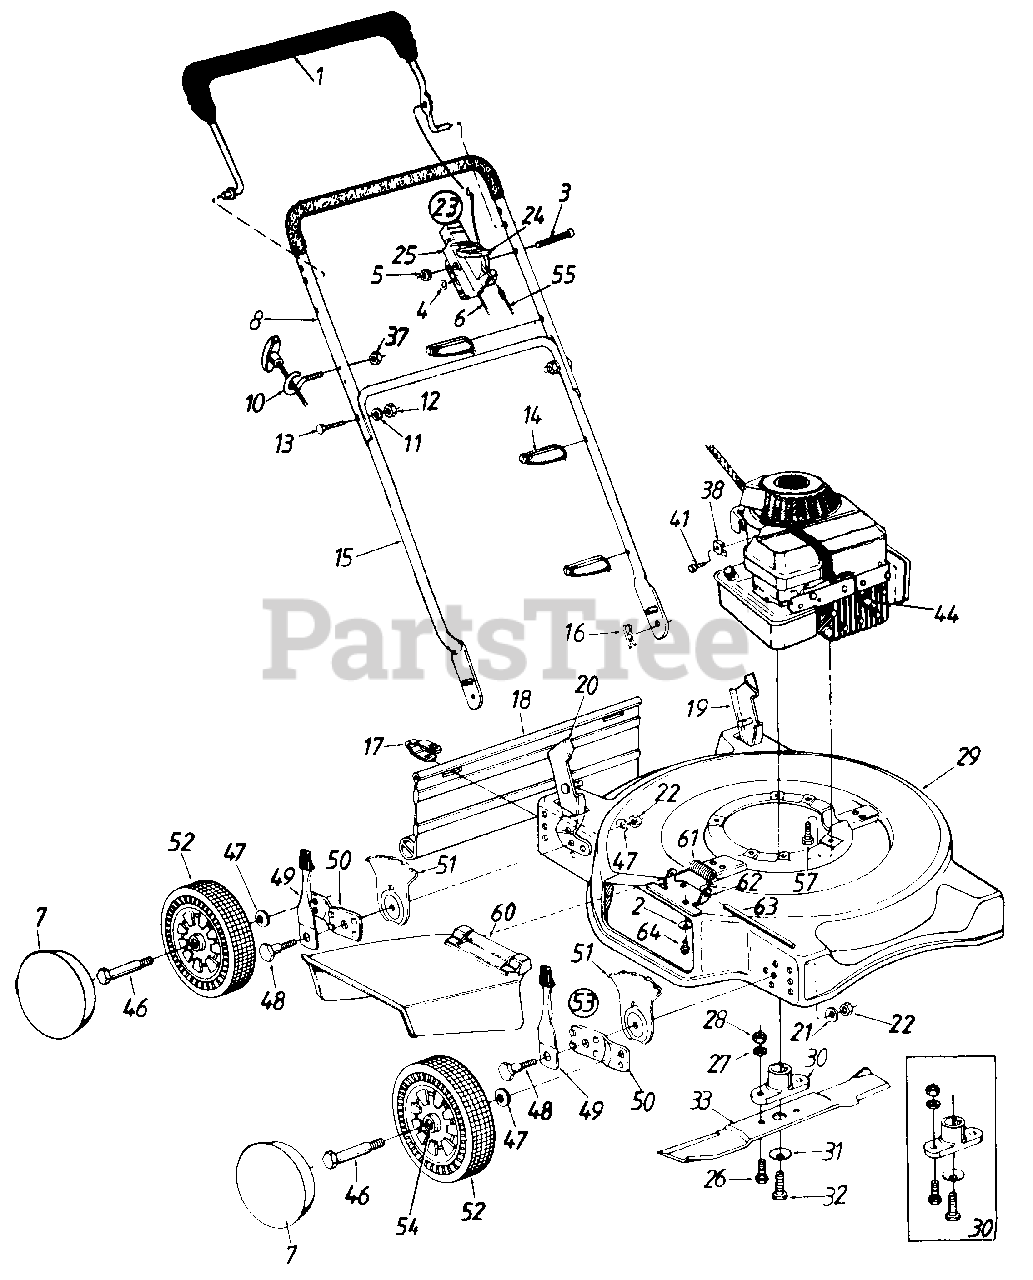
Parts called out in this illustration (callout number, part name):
1	Control Handle Ass'y.
2	Bell-Wash. 1/4" I.D.
3	Oval C-Sunk Scr.
4	Spr. Wash. .66" I.D.
5	Hex L-Nut 1/4-20 Thd.
6	Throttle Cable--51"
7	Hub Cap
11	L-Wash. 5/16" I.D.
12	Hex Nut 5/16-18 Thd.
13	Curved Carriage Bolt 5/16-18 x 1.38" Lg.
14	Cable Tie
15	Lower Handle
16	Hairpin Cotter
17	Hinge Clip
18	Rear Flap
19	Handle Bracket Ass'y.--L.H.
20	Handle Bracket Ass'y.--R.H.
21	Bell-Wash. .39" I.D. x 1.38"
22	Hex Nut 3/8-16 Thd.
23	Throttle Box Comp.
24	Throttle Lever
25	Throttle Body
26	Hex Bolt 3/8-24 x 1" Lg.
27	L-Wash. 3/8" I.D.
28	Hex Nut 3/8-24 Thd.
31	Bell-Wash. .39" I.D.
32	Hex Bolt 3/8-24 x 1.5" Lg.
33	20" Blade
37	Hex L-Nut 1/4-20 Thd.
38	Cable Clamp
41	Hex Self-Tap Scr. #10-32 x .62"
44	Spark Plug Boot
46	Axle Bolt
47	Bell-Wash. .400" I.D. x .88"
48	Shld. Bolt .50" Dia. x .357"
49	Spring Lever Ass'y. w/Knob
51	Height Adj. Plate
52	Wheel Ass'y. Comp.
53	Height Adj. Ass'y. Comp.--R.F. & L.R.
54	Wheel Bearing
55	Control Cable--39"
57	Hex L-Wash. Hd. Scr. 3/8-16 x 1.0" Lg.
60	Chute Deflector Ass'y.
61	Torsion Spring
62	Adapter Plate
63	Hinge Pin
64	Hex Self-Tap Scr. 1/4-20 x .5" Lg.
17036-0483	DECK ASSEMBLY-20INCHARCOAL - CHARCOAL GRAY (0483)
17036-0498	DECK ASSEMBLY-20IN(CUB YELLOW) - OLD CUB YELLOW (0498)
17036-0629	DECK ASSEMBLY-20INSILVER FLAK - SILVER FLAKE (0629)
17036-0638	DECK ASSEMBLY-20IN - MTD/TROY-BILT RED (0638)
17036-0662	DECK ASSEMBLY-20IN(OYSTER GRAY) - OYSTER GRAY (0662)
